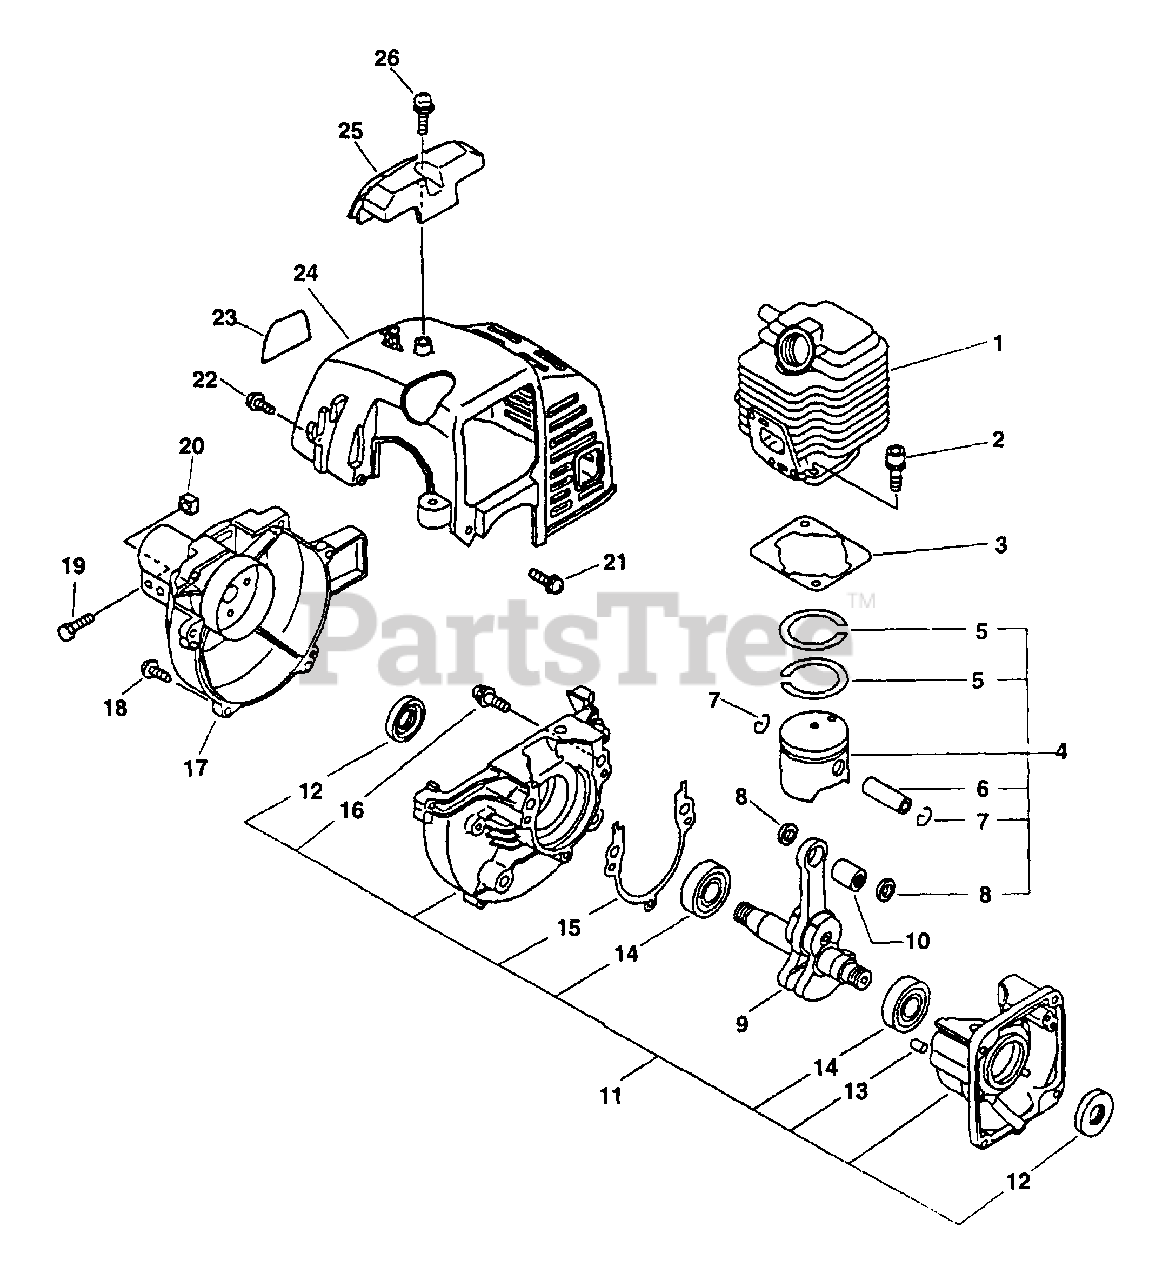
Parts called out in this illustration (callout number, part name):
1	CYLINDER
2	BOLT 5×22
3	GASKET, CYLINDER
4	PISTON KIT
5	RING, PISTON
6	PIN, PISTON 8
7	RING, SNAP
8	WASHER, THRUST
9	CRANKSHAFT
10	BEARING, NEEDLE
11	CRANKCASE KIT
12	SEAL, OIL 12
13	PIN, LOCATING 4
14	BEARING, BALL - 6201 C3
15	GASKET, CRANKCASE
16	BOLT 5×28
17	COVER ASSY, FAN
18	SCREW - 4×18
19	BOLT 5×28
20	NUT M5
21	SCREW 4×12
22	SCREW 4×16
23	LABEL, MODEL
24	COVER, ENGINE - GRAY
25	GUARD, TOP - GRAY
26	SCREW 5×16
